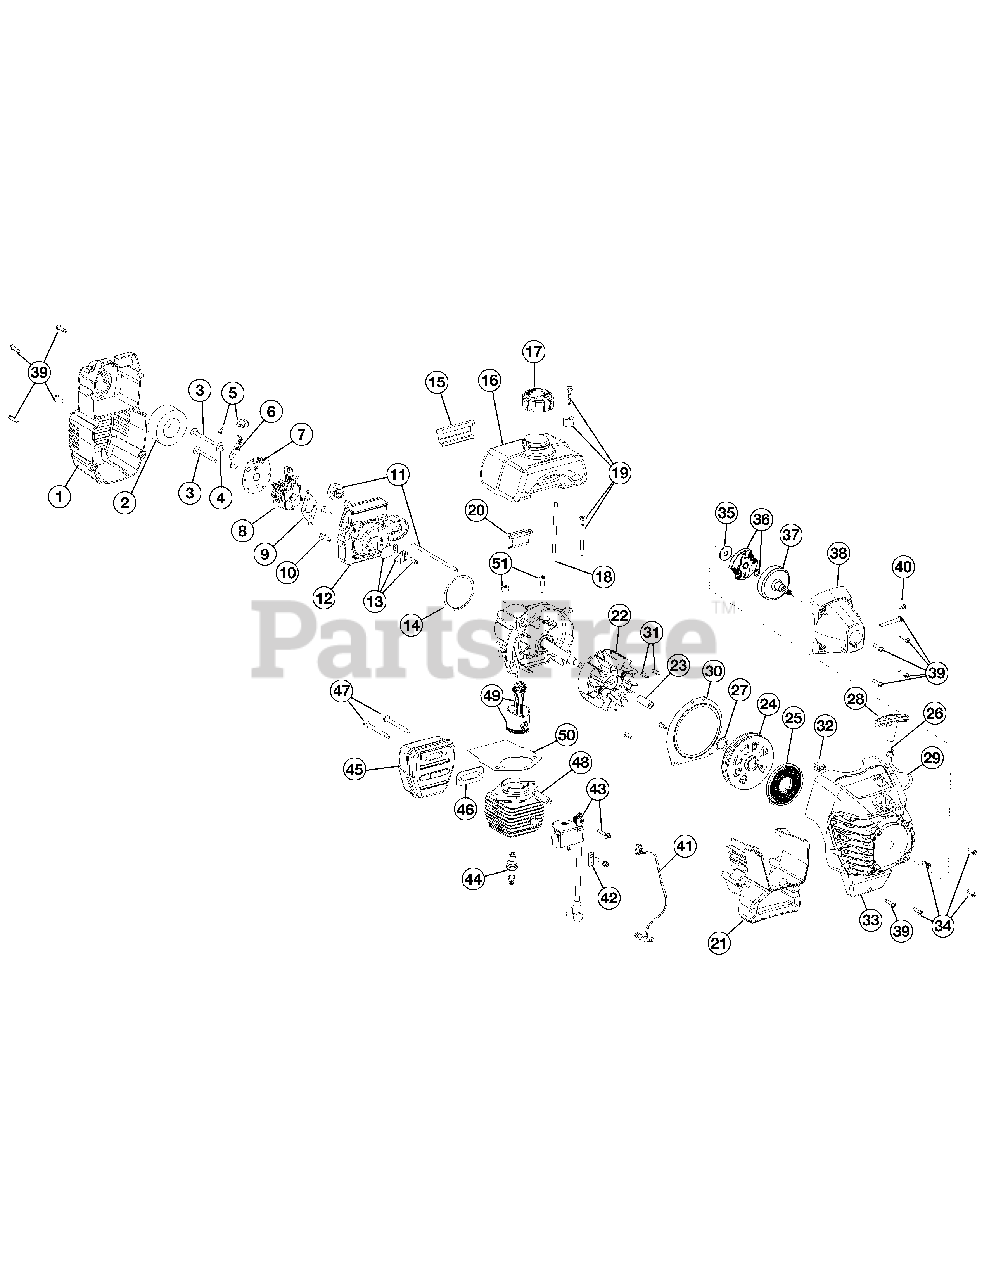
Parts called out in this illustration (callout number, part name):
1	Air Cleaner Cover Assembly (includes 2)
2	Air Cleaner Filter
3	Carburetor Mounting Screw Assembly
4	Wavey Washer
5	Choke Knob w/Screw
6	Choke Lever (includes 5)
7	Choke Plate (includes 6)
8	Carburetor Assembly (includes 9)
9	Carburetor Gasket
10	Carb Mount Screw
11	Primer & Hose Assembly
12	Carb Mount Assembly (includes 10, 13 & 14)
13	Reed Assembly
14	Carburetor O-Ring
15	Rear Mounting Pad
16	Fuel Tank Assembly (includes 17-19)
17	Fuel Cap Assembly
18	Fuel Return Line
19	Fuel Line Assembly
20	Front Mounting Pad
21	Shroud Extension & Stand (includes 39)
22	Flywheel Assembly
24	Recoil Pulley Assembly (includes 25, 27 & 29)
25	Recoil Spring
26	Rope Guide
27	Pulley Retainer
28	Pull Handle
30	Pressure Plate Assembly (includes 31)
31	Plate Screw
32	Rope Guide Retainer
33	Starter Housing Assembly (includes 24-32, 34 & 39)
34	Housing Screw
35	Clutch Washer
36	Clutch Rotor Assembly
37	Clutch Drum Assembly
38	Clutch Cover Assembly (includes 39-40)
39	Cover Screw
40	Anti-Rotation Screw
41	Wire Leads and Sleeve
42	Ground Tab
43	Module Assembly
44	Spark Plug
45	Muffler Assembly (includes 46 & 47)
46	Exhaust Gasket
47	Muffler Mounting Bolts
48	Cylinder Assembly (includes 50 & 51)
49	Piston and Rod Assembly
50	Cylinder Gasket
51	Cylinder Bolt
